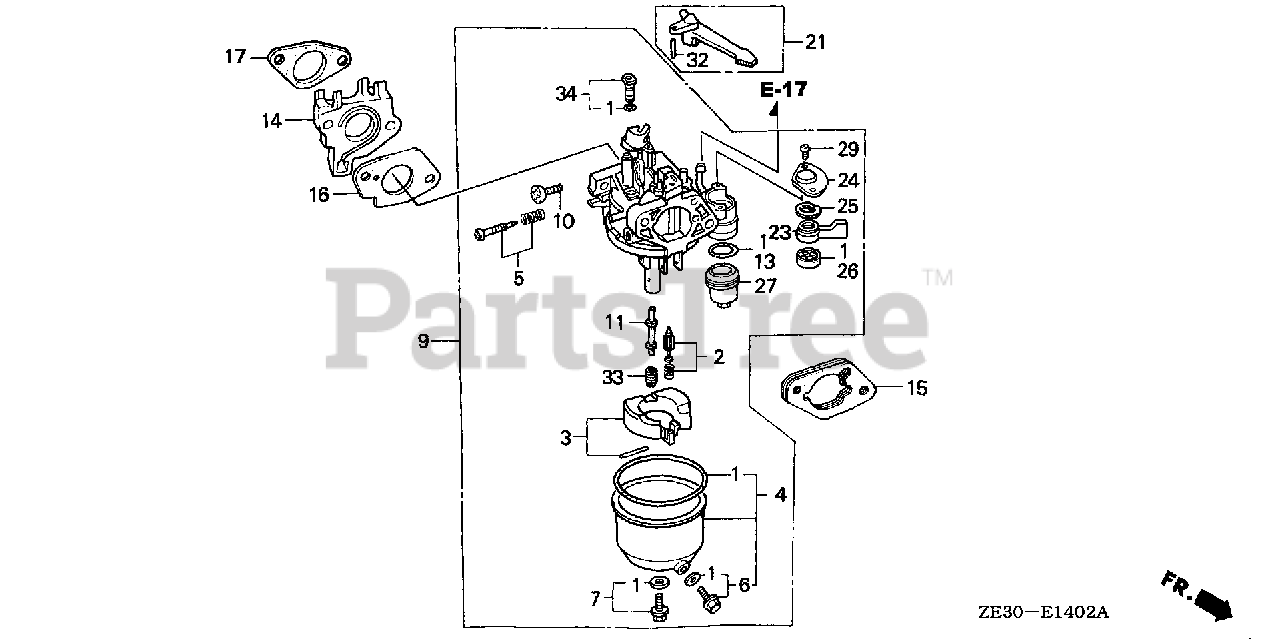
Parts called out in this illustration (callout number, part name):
1	GASKET SET (INCLUDES 16173-001-004)
2	VALVE SET, FLOAT
3	FLOAT SET
4	CHAMBER SET, FLOAT
5	SCREW SET, PILOT
6	SCREW SET, DRAIN
7	SCREW SET
9	CARBURETOR ASSY. (BE18A C) (NOT AVAILABLE)
10	SCREW, THROTTLE STOP
11	NOZZLE, MAIN
13	GASKET, FUEL STRAINER CUP
14	INSULATOR, CARBURETOR
15	SPACER, CARBURETOR
16	GASKET, CARBURETOR
17	GASKET, INSULATOR
21	LEVER, CHOKE (STD)
23	LEVER, VALVE
24	PLATE, LEVER SETTING
25	SPRING, PETCOCK LEVER
26	GASKET, PETCOCK
27	CUP, FUEL STRAINER
29	SCREW, PAN (3X8)
32	PIN, SPRING (2X12)
33	JET, MAIN (#100)
33	JET, MAIN (#102)
33	JET, MAIN (#105)
34	JET SET, PILOT (#35)
